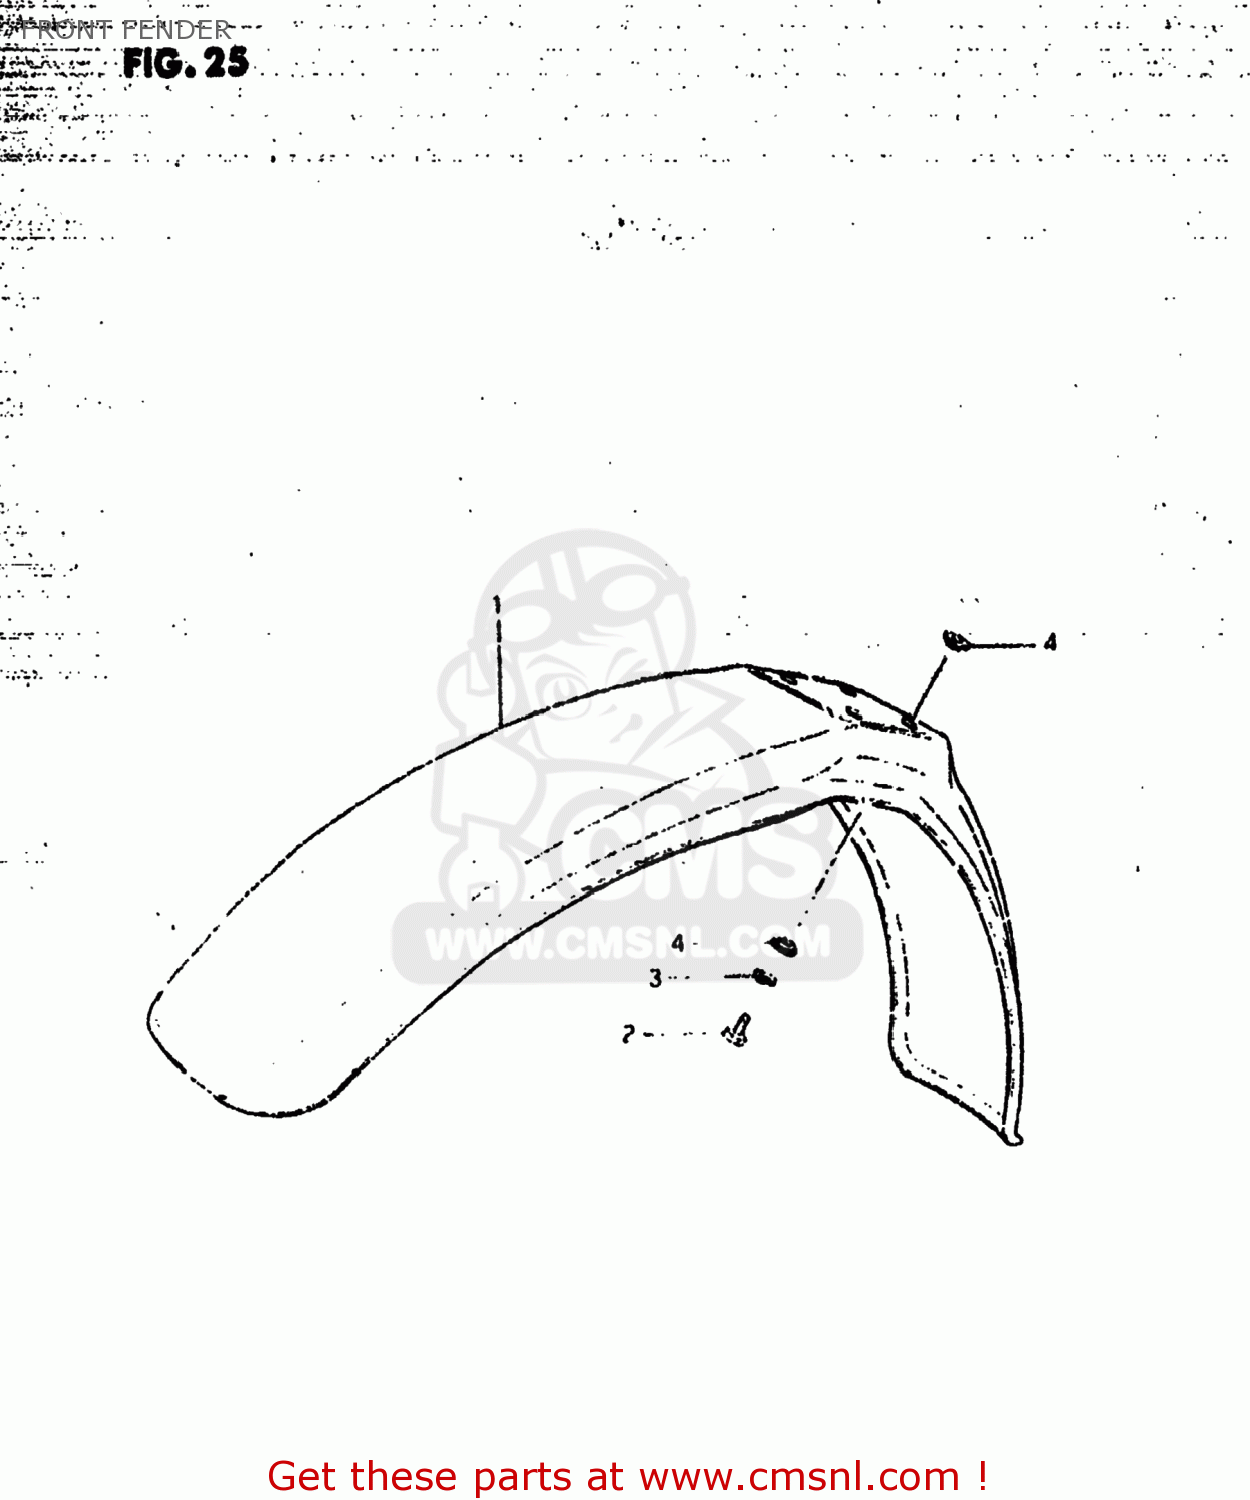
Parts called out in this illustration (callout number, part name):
1	FENDER,FR
2	BOLT, UPPER
3	LOCK WASHER
4	SPACER
